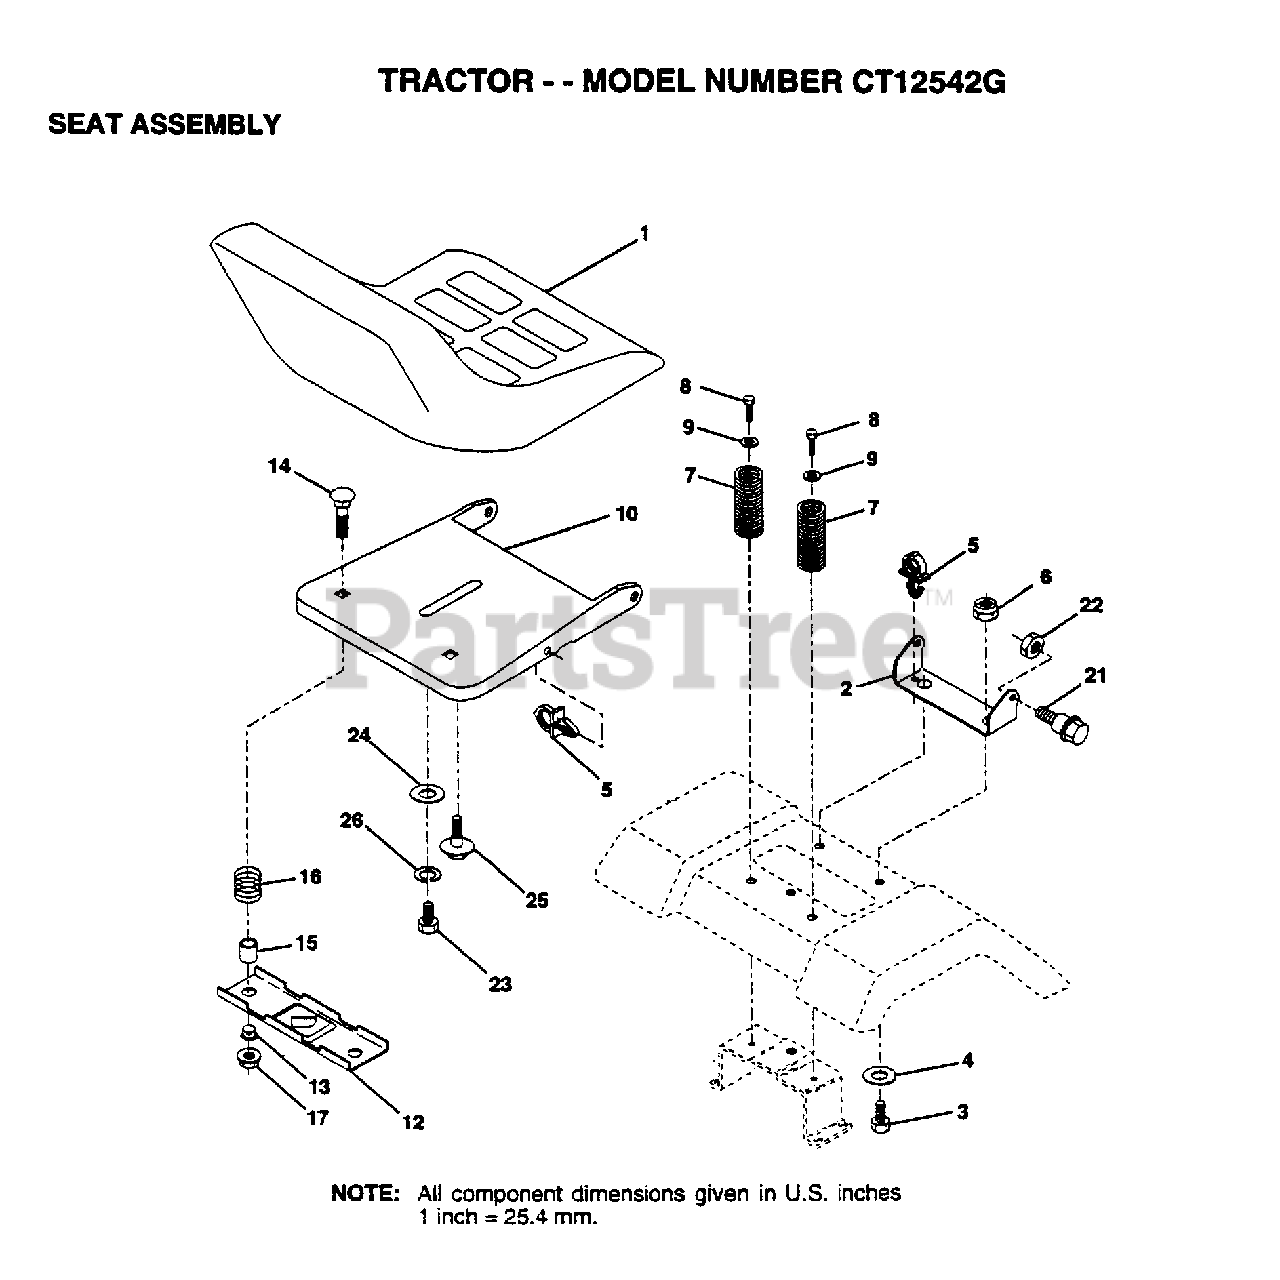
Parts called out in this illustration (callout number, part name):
2	BRACKET PVT SEAT
3	BOLT
4	WASHER PM
5	CLIP.PUSH-IN.HING
6	NUT
7	SPRING COMPRESSIO
8	SCREW GTV
9	WASHER
12	BRKT SWITCH
13	BUSHING
15	SPLIT SPACER
16	SPRING
21	BOLT.SHLD.5/16-18
22	NUT
23	BOLT
24	WASHER
25	"BOLT,SHOULDER"
26	LOCKWASHER
